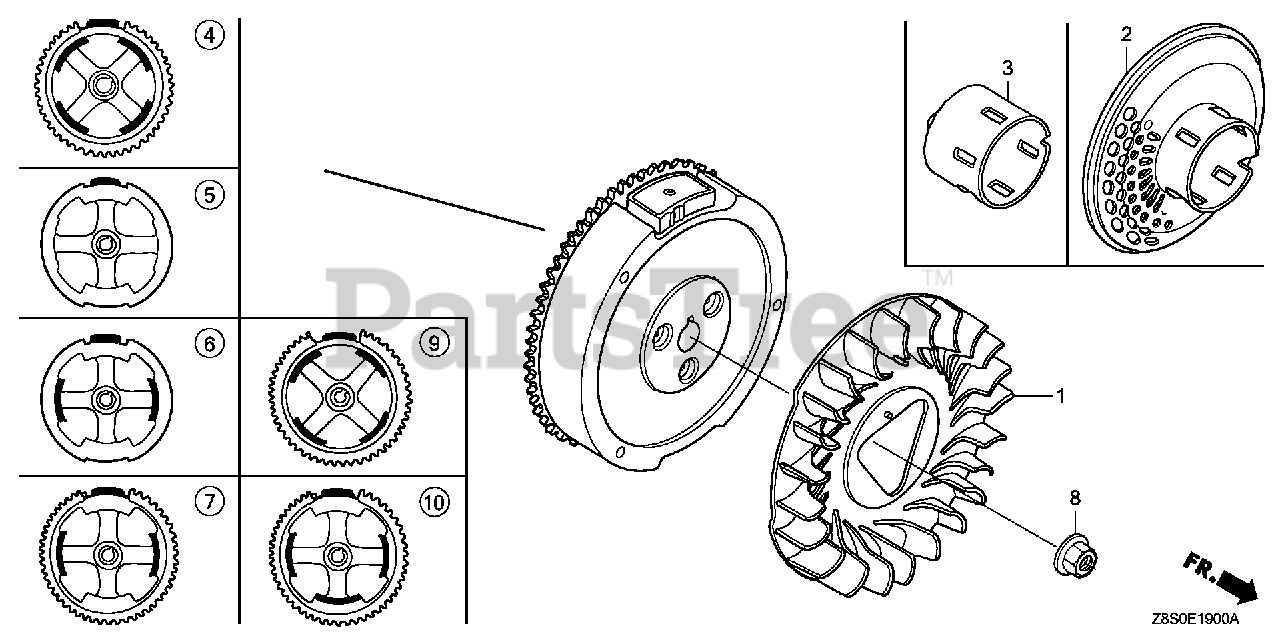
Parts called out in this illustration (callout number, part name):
1	FAN, COOLING
3	PULLEY, STARTER
8	NUT, SPECIAL (16MM) (1)
